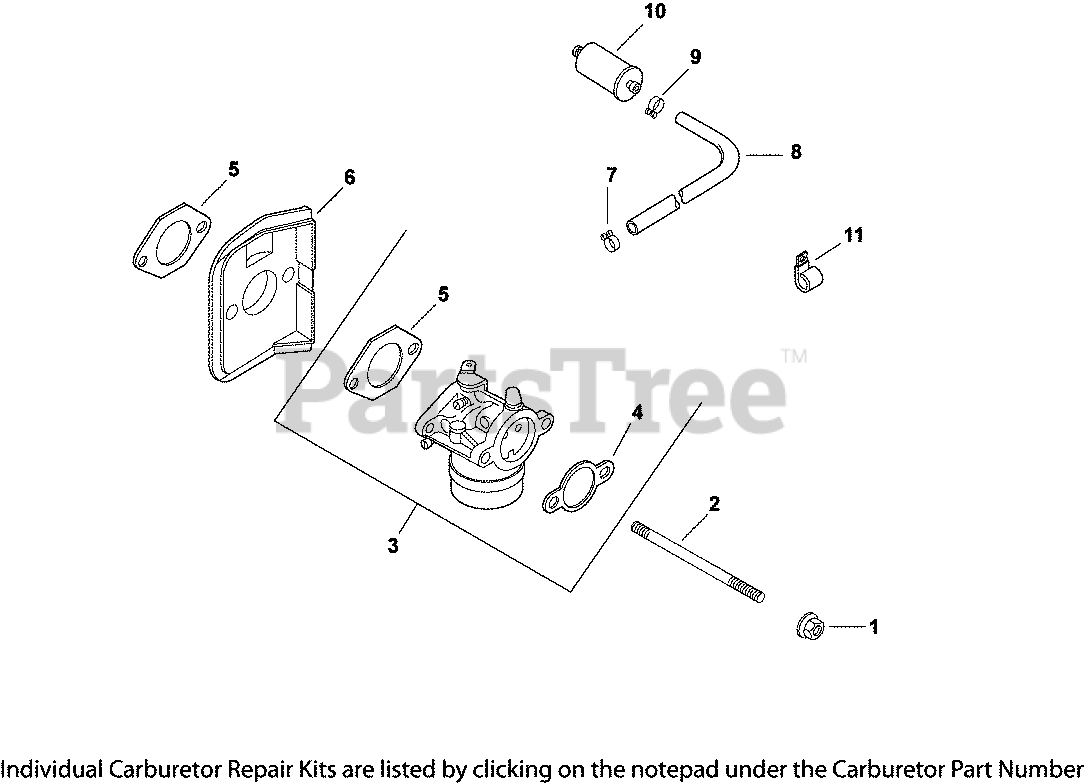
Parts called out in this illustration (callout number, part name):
1	NUT, FLG M6X1.0
2	STUD,M6X1.0X116
3	KIT, CARB W/GASKETS - USE 12 853 177-S
4	GASKET, AIR CLEANER BASE
5	GASKET, CARBURETOR
6	DEFLECTOR, HEAT
7	CLAMP, HOSE (KM)-USE 25 237 31-S
8	HOSE,LW PERM.FUEL 24.00"-USE 25 111 81-S
9	CLAMP, BAND SPRING HOSE-(#2523737S)
10	FILTR,FUEL 75 MICRON (GRAVTY FEED)
11	CLIP, CABLE
